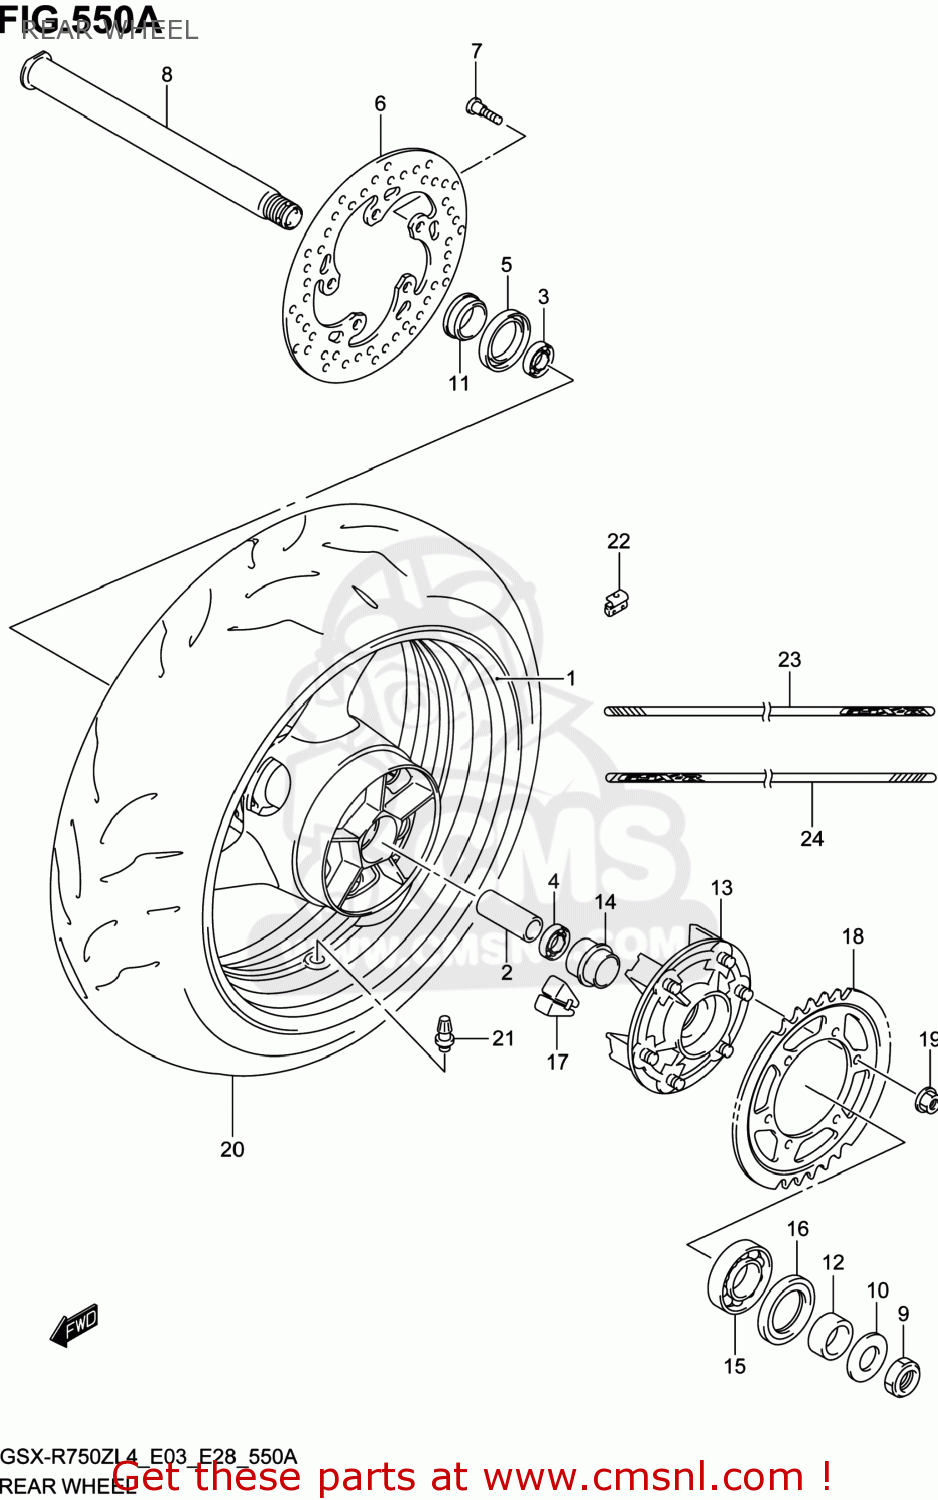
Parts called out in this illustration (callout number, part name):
1	WHEEL,RR(17M/CXMT5.50)
2	SPACER,RR WHEEL BEARING
3	BEARING(25X52X15)
4	BEARING
5	SEAL,OIL(32X52X7)
6	DISC,RR BRAKE
7	BOLT(8X21)
8	AXLE,RR
9	NUT
10	WASHER(22X35X2)
11	SPACER,FR AXLE,R
12	SPACER,RR AXLE,L
13	DRUM,RR SPROCKET
14	RETAINER,RR SPROCKET DRUM
15	BEARING(32X65X17)
16	SEAL,OIL(39X65X7)
17	ABSORBER,RR HUB SHOCK
18	SPROCKET,RR(45T-525)
19	NUT
20	TIRE,RR
21	VALVE ASSY,WHEEL RIM(TR412)
22	BALANCER,WHEEL(10G)
23	TAPE,WHEEL FRONT,R
24	TAPE,WHEEL FRONT,L
